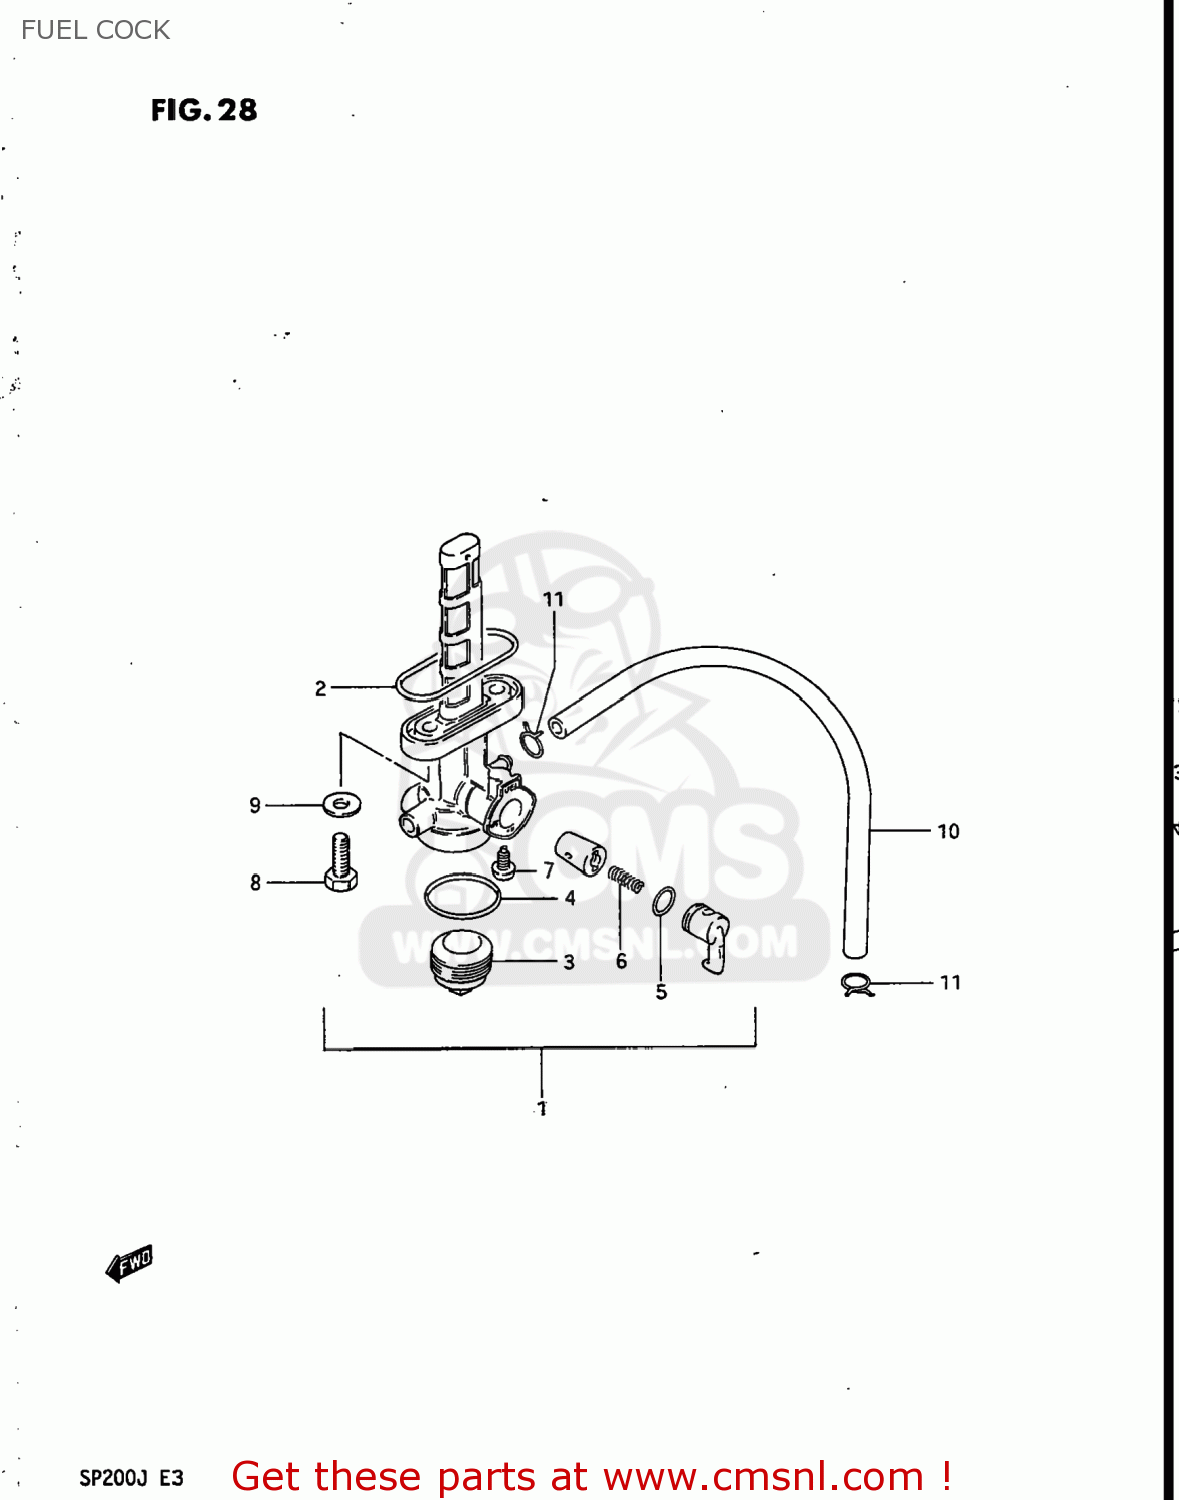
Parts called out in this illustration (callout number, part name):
1	COCK ASSEMBLY,FUEL
2	O RING,FUEL COCK
3	CUP,STRAINER
4	GASKET,FILTER (NAS)
5	O-RING
6	SPRING
7	SCREW
8	BOLT(6X20)
9	GASKET
10	HOSE
11	CLIP
